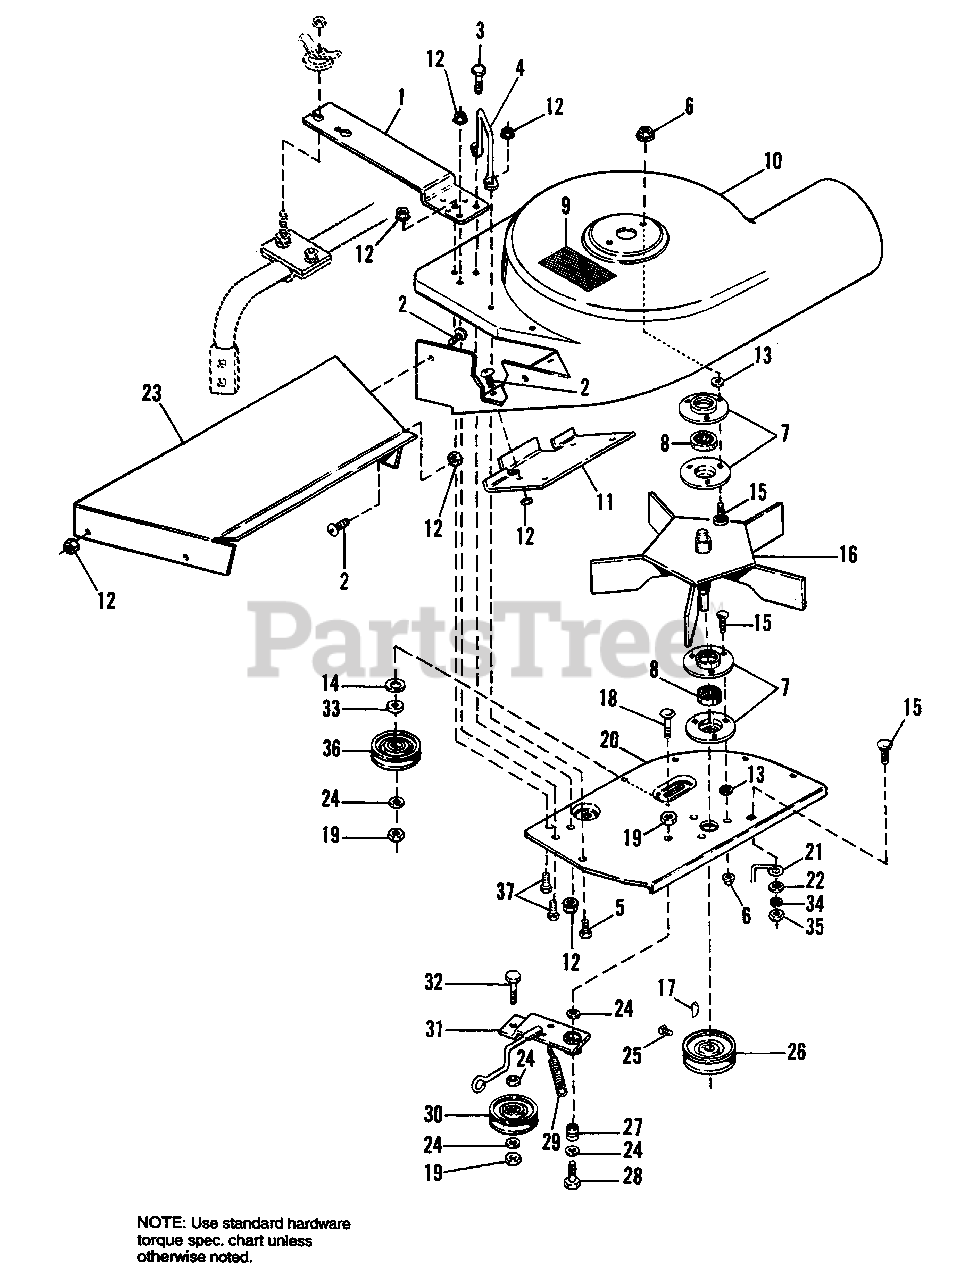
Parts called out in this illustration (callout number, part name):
1	MOUNTING PLATE, 60"
2	SCREW, Hex Hd., 1/4-20 x 5/8
3	CAPSCREW, Hex, 1/4-20 x 2-1/4
4	STOP, Deflector
5	CAPSCREW, Hex, 1/4-20 x 7/8
6	NUT, Flange, Lock, 5/16-18
7	BEARING, Retainer
9	DECAL, Warning
10	TURBO HOUSING,
11	HOOK, Stoneguard
12	NUT, Hex Flange Whiz, 1/4-20
13	PUSH NUT, Nylon, 1/4-20
14	WASHER, Plain, 1/2
15	CARRIAGE BOLT, 5/16-18 x 3/4
16	FAN ASSY. (5 Blade)
17	KEY, Woodruff
18	CARRIAGE BOLT, 3/8-16 x 1-1/4
19	NUT, Hex Jam Lock, 3/8-16
20	PLATE, Shroud
22	WASHER, Plain, 11/32
24	WASHER, 13/32
25	SETSCREW, Sq. Hd., 5/16-18 x 3/8
26	PULLEY, Driven
27	SPACER
28	CAPSCREW, Hex Hd., 3/8-16 x 1/2
29	SPRING, Tension
30	PULLEY, Idler, Adjustable
31	IDLER ARM ASSY.
32	CAPSCREW, 3/8-16 x 1
33	WASHER, Special
34	LOCKWASHER, 5/16
35	NUT, Hex, 5/16
36	PULLEY, Idler,
37	CAPSCREW, Hex Hd., 1/4-20 x 3/4
